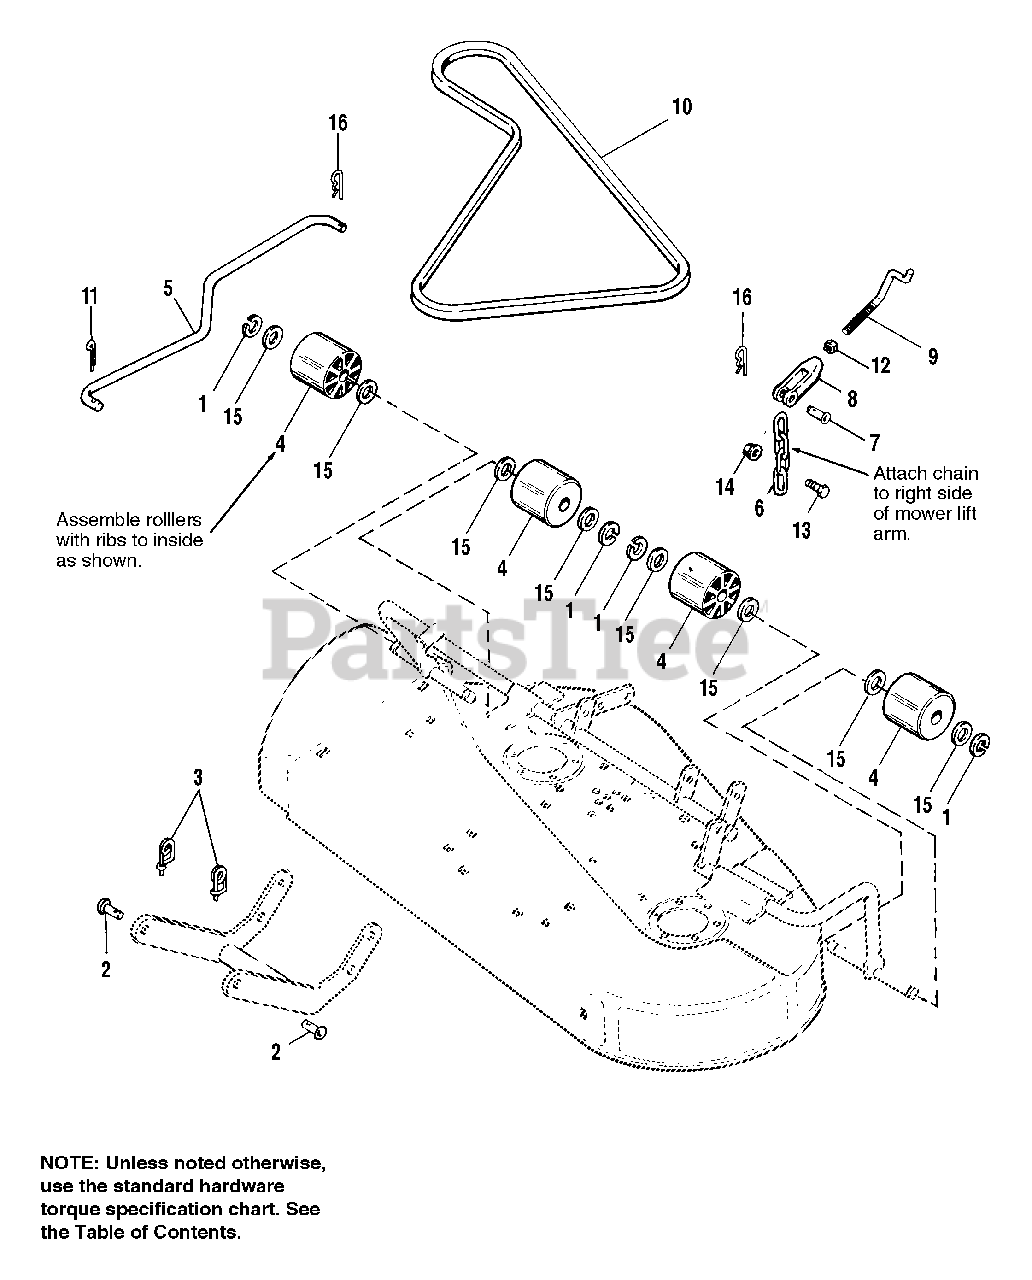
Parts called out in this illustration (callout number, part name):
1	RING, Retaining
3	CLIP, Safety
5	ROD, P.T.O.
6	CHAIN, Lift 4 Links
7	PIN, Rivet
8	CLEVIS, Pin
10	V-BELT, Mower Drive
11	PIN, Cotter, 3/32 x 1
12	NUT, Jam, 5/16-18
13	CAPSCREW, Hex Hd., 5/16-18 x 1
14	LOCKNUT, Hex, Flange, 5/16-18
15	WASHER, Plain, 5/8
16	CLIP, Hairpin
